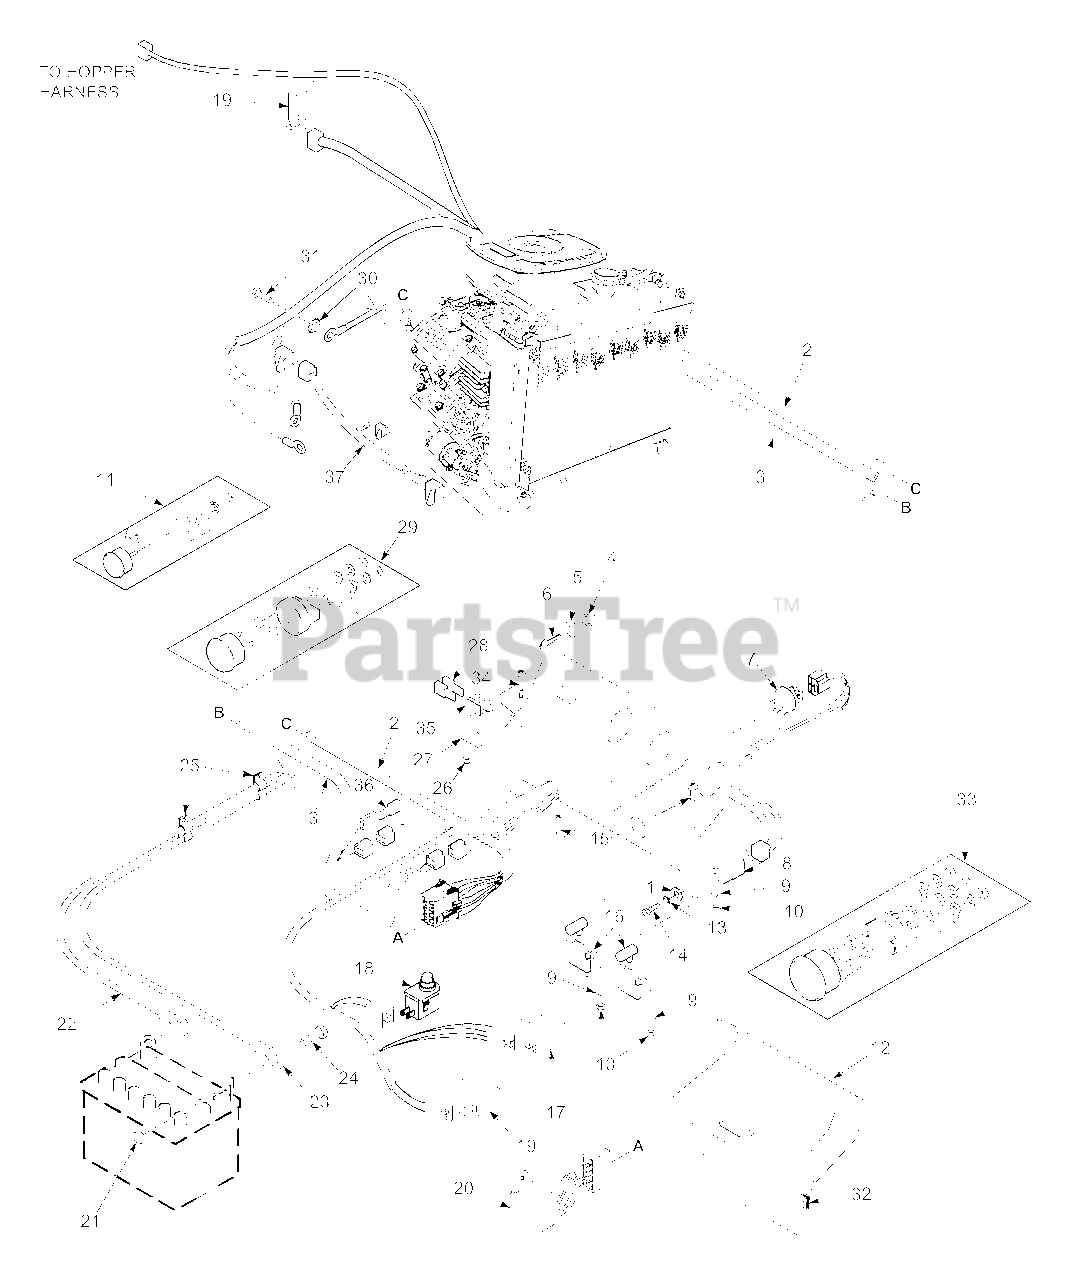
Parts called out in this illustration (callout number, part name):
1	Flatwasher, 5/16-.375 x .875 x .083
2	Wire Harness, SCR
3	Wire Harness, Hopper
4	Lockwasher, Internal 5/8"
5	Nut, 5/8-32 Special
6	Key & Ring
7	Keyswitch w/hardware
8	Relay
9	Lockwasher, #10 external tooth
10	Nut, #10-32 UNF
11	Hour Meter
12	Instrument Panel, Lower
13	Lockwasher, 5/16
14	Bolt, Hex Head 5/16-18 x 1"
15	Screw, #10-32 x 1/2"
16	Control Cable
17	Switch, PTO
18	Switch, Seat
19	Switch, Brake & Hopper
20	Interlock Module
21	Nut, 1/4-20
22	Battery Cable, Black
23	Battery Cable, Red
24	Bolt, Hex Head 1/4-20 x 1/2"
25	Cable Clamp, Double
26	Nut, Elastic Stop #10
27	Bracket, Fuse Holder
28	Fuse, 20 Amp
29	Ammeter
30	Lockwasher, 3/8"
31	Bolt, Hex Head
32	U-Nut, 5/16-18
33	Water Temp Gauge
34	Screw, #10-32 x 1-1/2"
35	Fuse Holder W/Fuse & Connector
36	Fuse, 15 Amp
37	Wire Harness, Engine SCR 27KA
